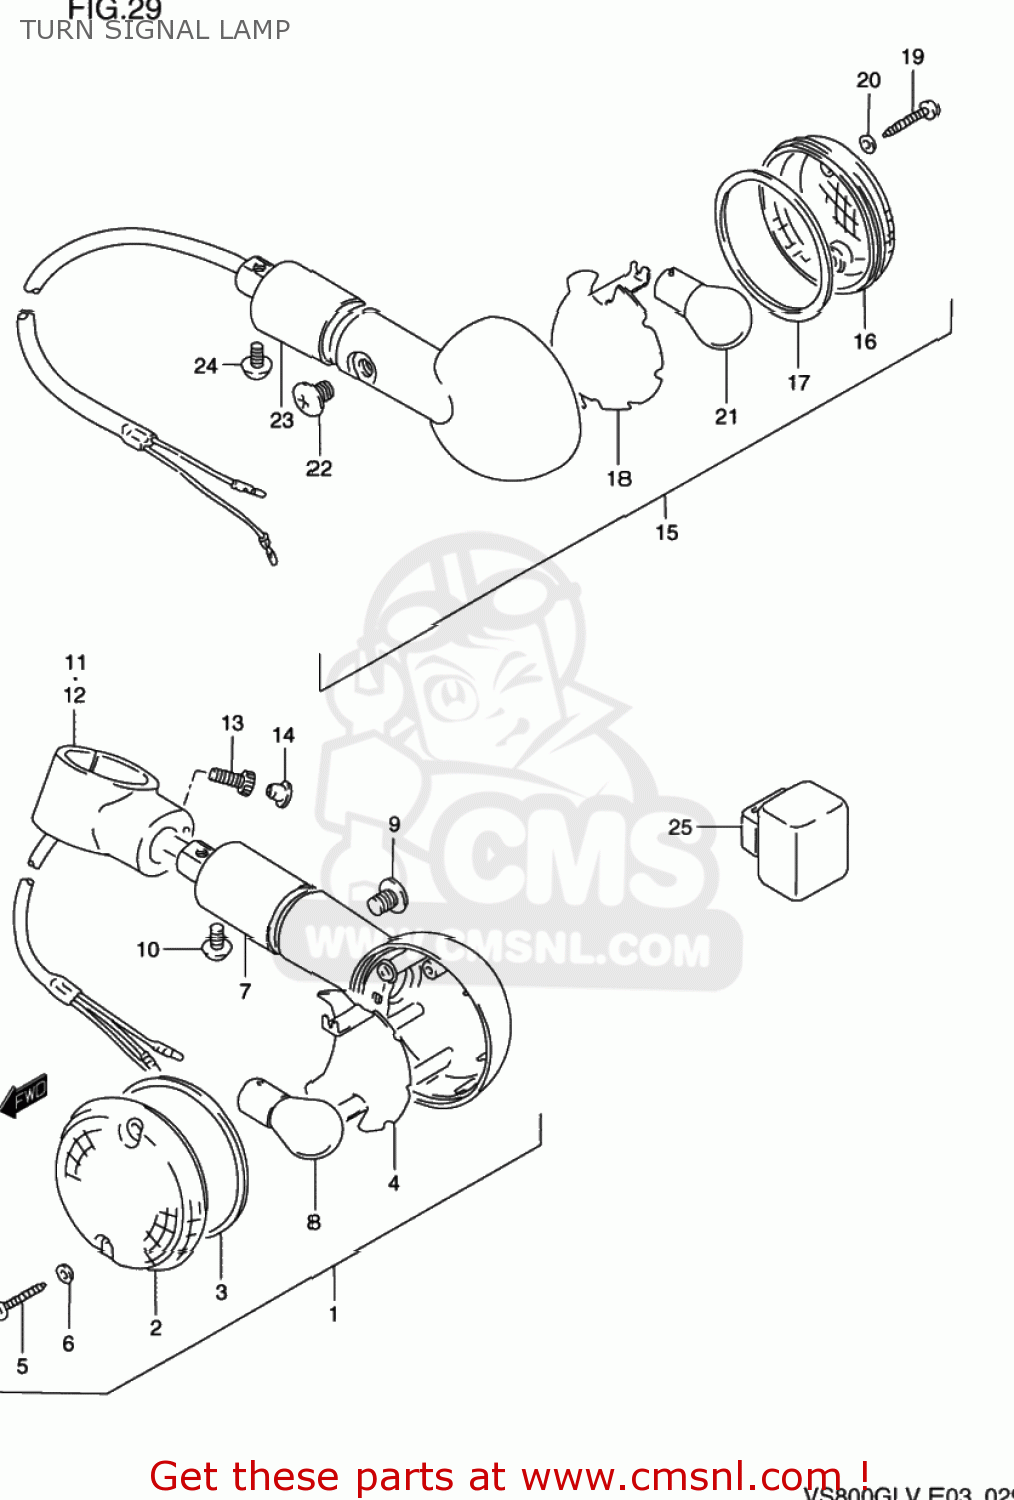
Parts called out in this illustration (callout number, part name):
1	LAMP ASSEMBLY,FRONT TURN SIGNAL
2	LENS
3	GASKET (NAS)
4	REFRECTOR
5	SCREW
6	GASKET (NAS)
7	STAY,TURNSIGNAL LAMP
8	BULB(12V21/5W,BF141-49642A)
9	SCREW
10	SCREW
11	BRACKET,FR TURNSIGNAL LAMP,R
12	BRACKET,FR TURNSIGNAL LAMP,L
13	BOLT
14	CAP(OD:10)
15	LAMP ASSEMBLY,REAR TURN SIGNAL
16	LENS
17	GASKET (NAS)
18	REFRECTOR
19	SCREW
20	GASKET (NAS)
21	BULB(12V21W)
22	SCREW
23	STAY,TURNSIGNAL LAMP
24	SCREW
25	RELAY,TURN SIGNAL
